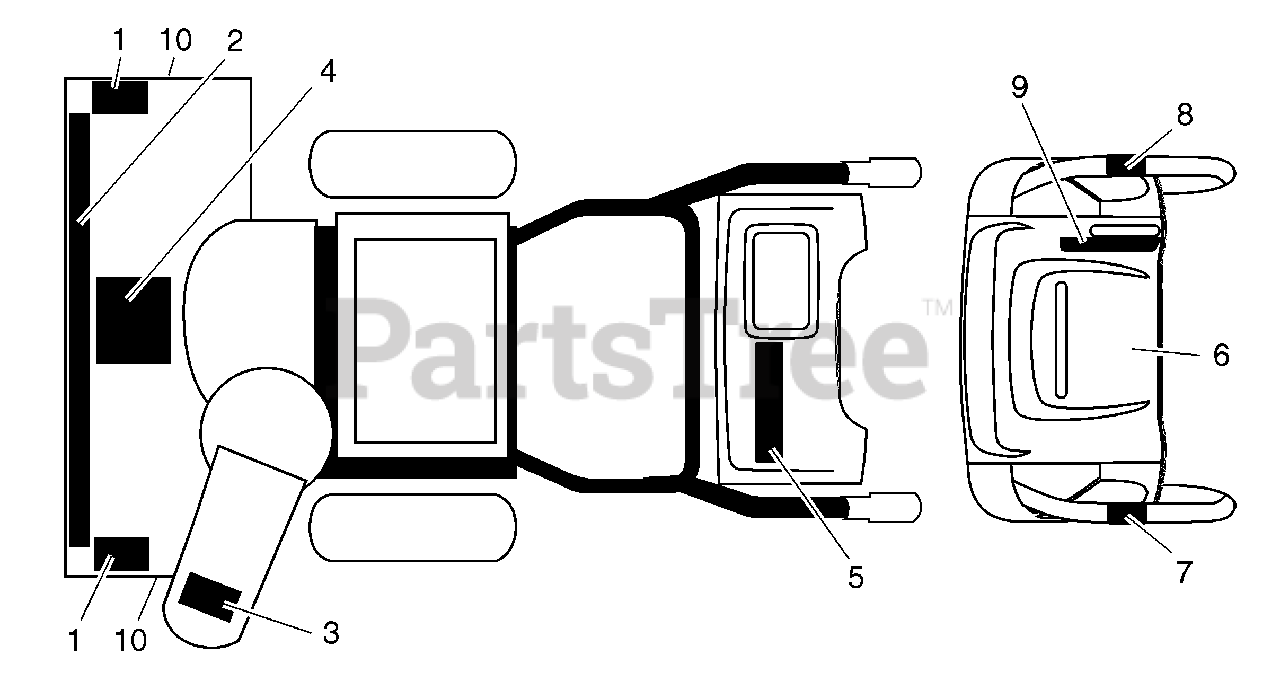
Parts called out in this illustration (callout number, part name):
1	Decal, Danger
2	Decal, Husqvarna
3	Decal, Danger, Deflector
4	Decal, Danger
5	Decal, Husqvarna, 924SBE
6	Decal, Instruction
7	Decal, Traction Lever
8	Decal, Auger Lever
9	Decal, Speed Control
10	Decal, Husqvarna, Crown
